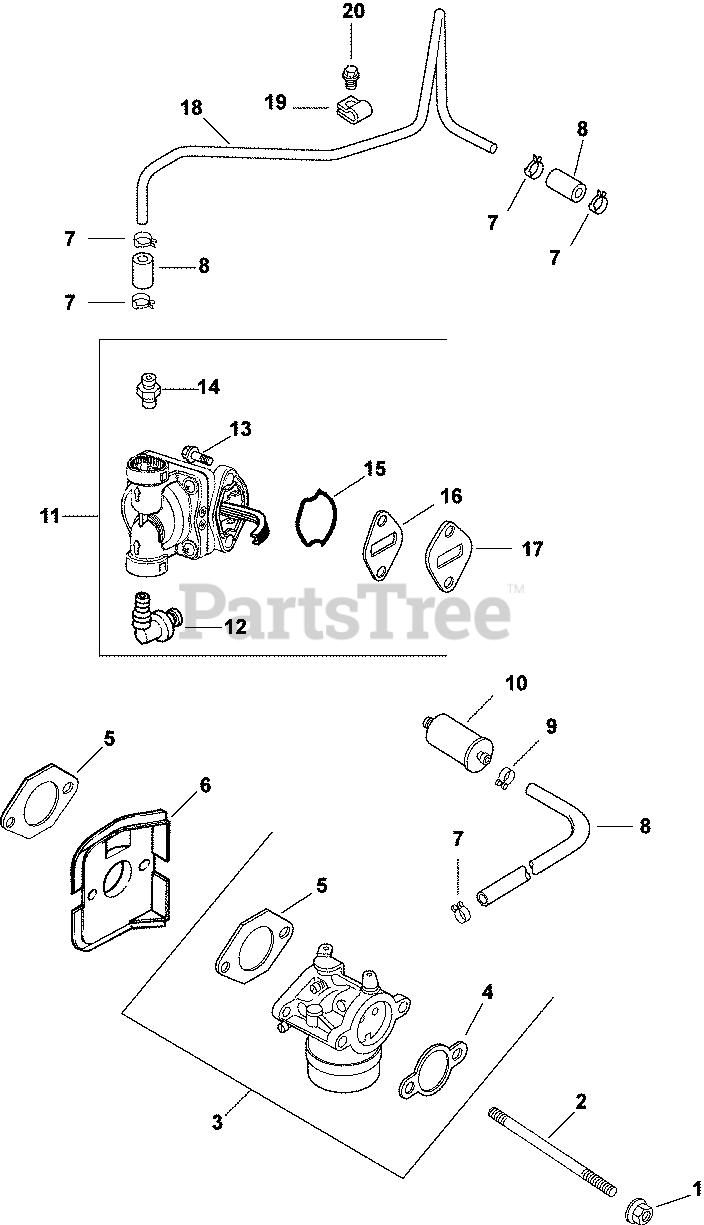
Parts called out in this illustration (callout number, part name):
1	NUT, FLG M6X1.0
2	STUD,M6X1.0X116
3	CARBURETOR W/GASEKTS - USE 12 853 139-S
4	GASKET, AIR CLEANER BASE
5	GASKET, CARBURETOR
6	DEFLECTOR, HEAT
7	CLAMP, BAND SPRING HOSE-(#2523737S)
8	HOSE,LW PERM.FUEL 24.00"-USE 25 111 81-S
9	CLAMP, HOSE (KM)-USE 25 237 31-S
10	FILTR,FUEL 75 MICRON (GRAVTY FEED)
11	KIT, FUEL PUMP
12	CONNECTOR, 90 DEG. HOSE
13	SCREW, LBD SKT M6x1.0x20-(#25086403S)
14	KIT, STRAIGHT FITTING
15	O-RING, FUEL PUMP
16	GASKET, FUEL PUMP
17	SPACER, FUEL PUMP
18	LINE, FUEL
19	CLIP, TUBE & WIRING (KM)
20	SCREW, FLG THD FRM M5X.8X10
